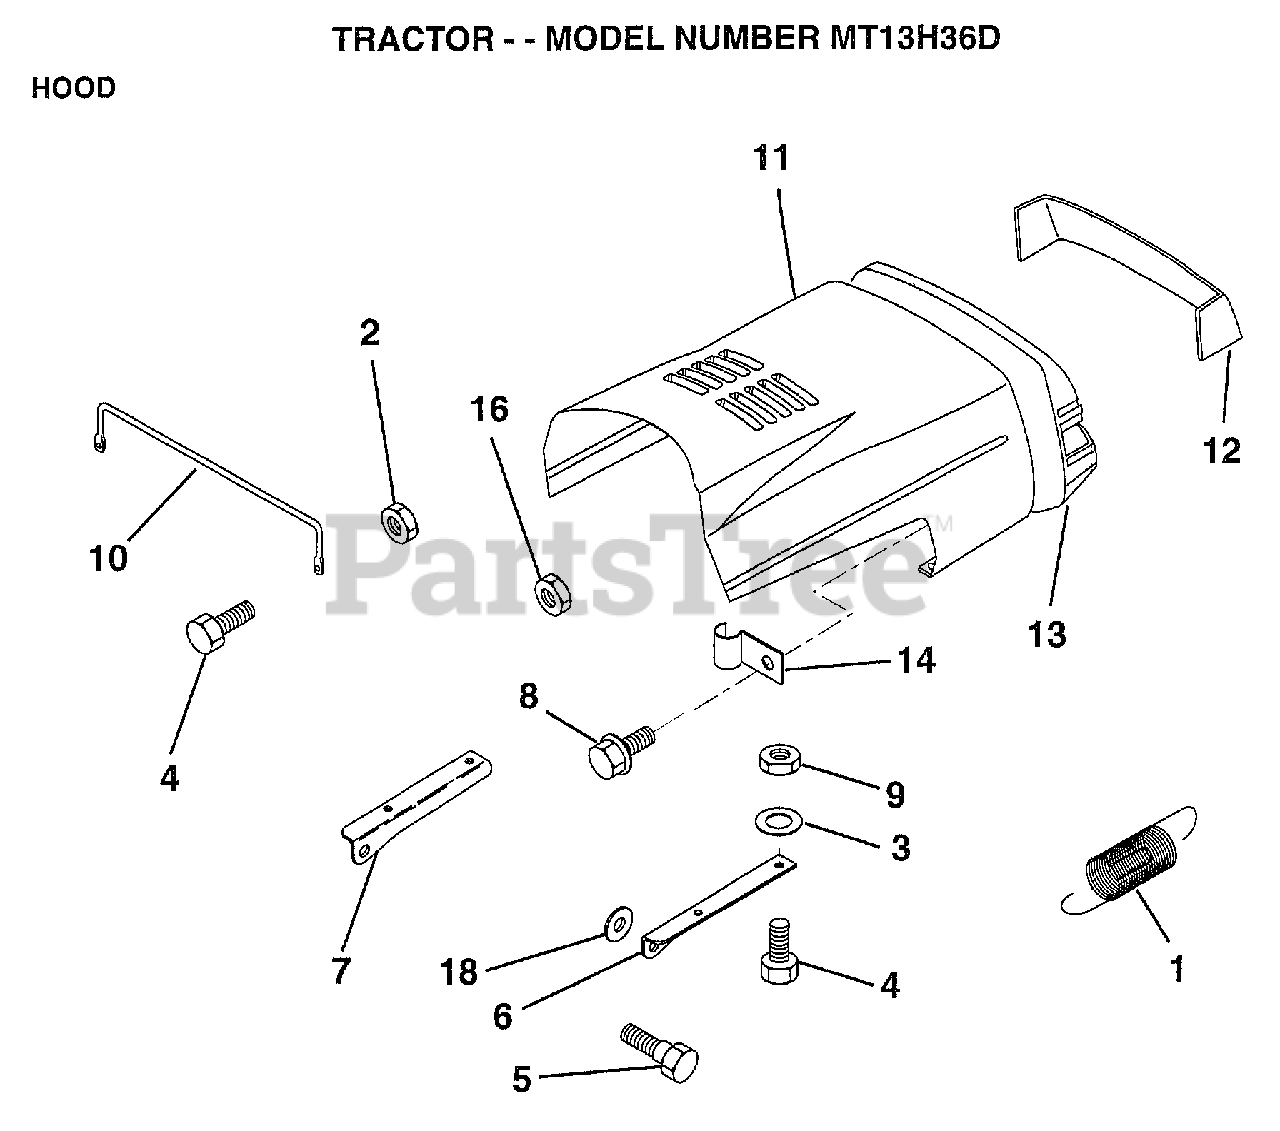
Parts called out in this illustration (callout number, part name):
1	EXT SPRING
2	NUT
3	WASHER
5	BOLT.SHLD.5/16-18
6	BRKT HOOD RH
7	BRKT HOOD LH
8	"SCREW,HWHD.HI-LO#13-16X3/4"
9	NUT
10	"BRACE,HOOD"
11	HOOD
12	LENS.BAR.CLEAR.LR
13	GRILL
16	NUT
18	WASHER
